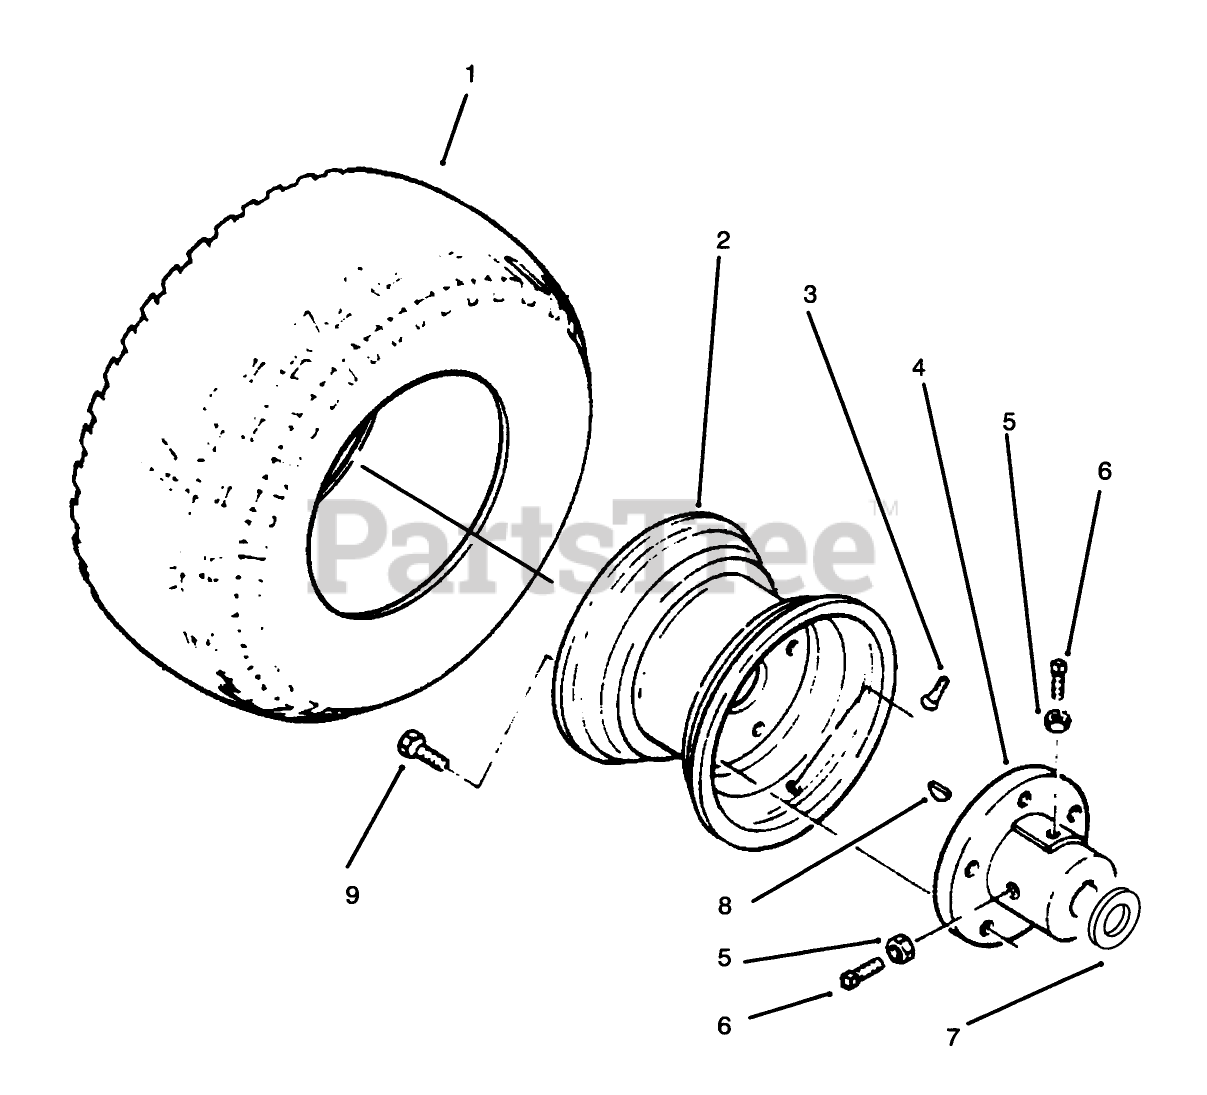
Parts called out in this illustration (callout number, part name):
1	TIRE
2	WHEEL
3	VALVE
4	Hub Rear
5	NUT-JAM
6	SCREW-SET, SQH
7	WASHER-THRUST
8	KEY-WOODRUFF
9	BOLT-LUG
